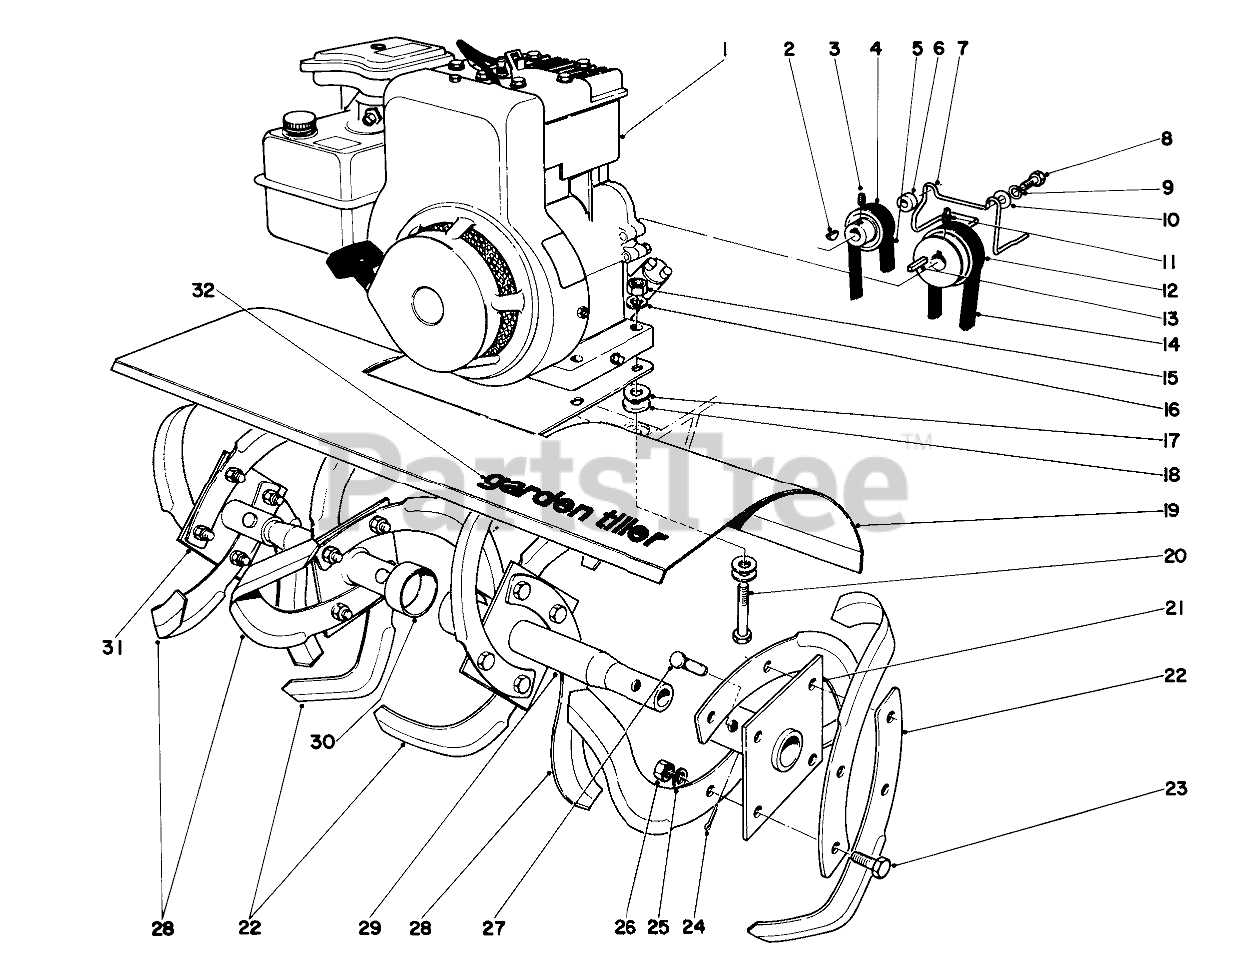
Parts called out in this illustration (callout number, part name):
1	Engine
2	KEY-WOODRUFF
3	SCREW-SET
4	PULLEY
5	V-BELT
6	SPACER
7	BELT GUIDE
8	SCREW-HH
9	WASHER-LOCK
10	WASHER-FLAT
11	SCREW-SET, HSH
12	Engine Pulley
13	KEY-SQUARE
14	Belt
15	NUT-HEX
16	WASHER-LOCK
17	WASHER-FLAT
18	WASHER-FLAT
19	Shield
20	SCREW-HH
21	Axle L.H.Outer
22	RH TINE
23	SCREW-HH
24	PIN-COTTER
25	WASHER-LOCK
26	NUT-HEX
27	TINE PIN
28	LH TINE
29	Axle L.H. Inner
30	Axle R.H. Inner
31	Axle R.H. Outer
32	Decal
